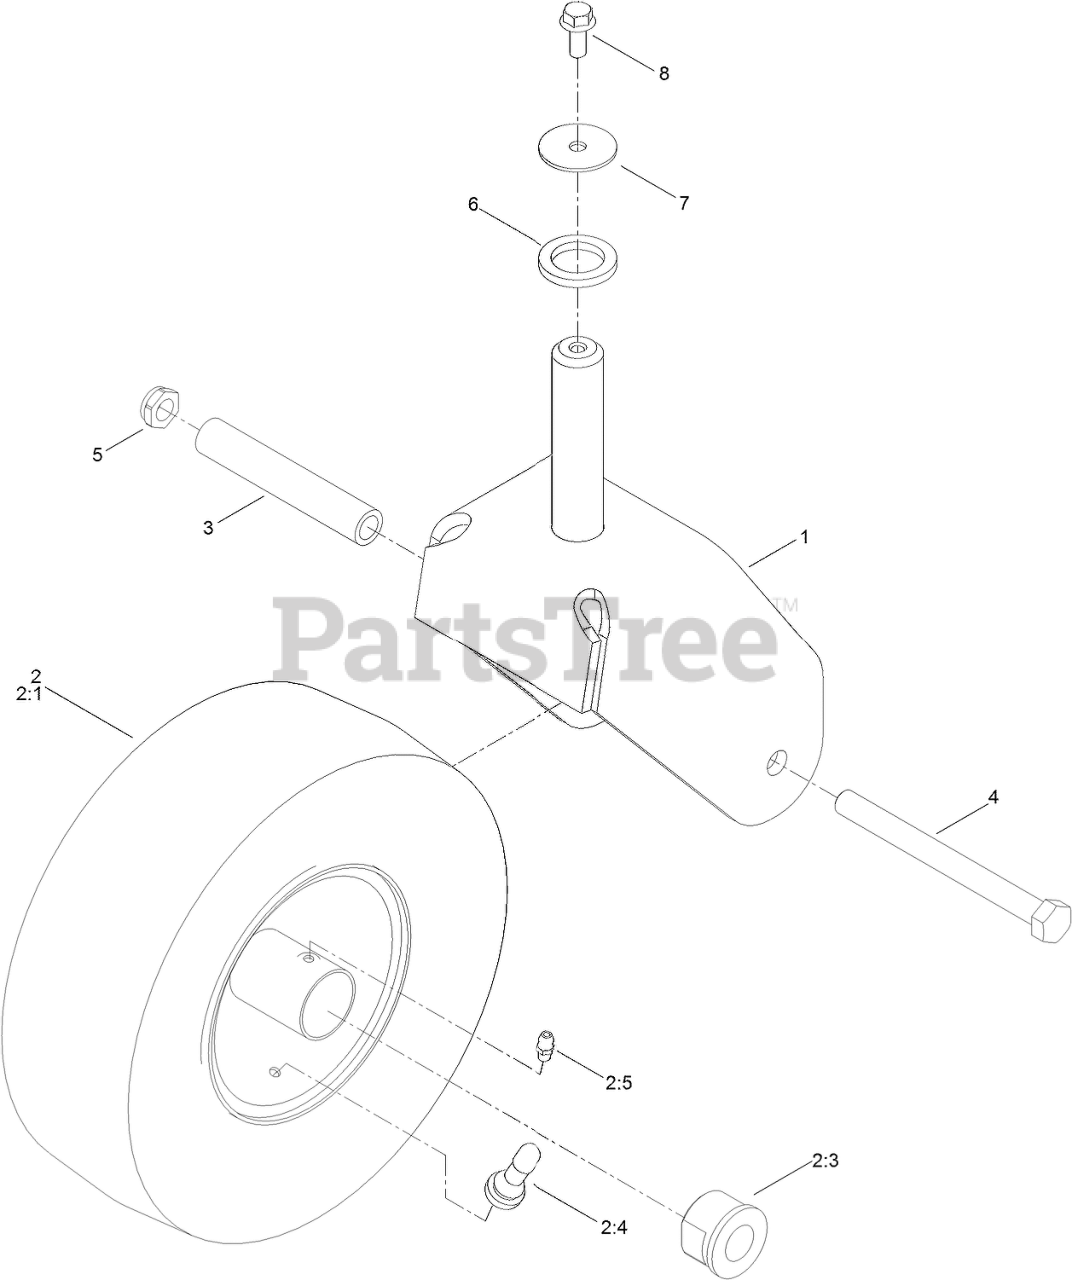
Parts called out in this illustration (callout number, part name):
1	FORK-CASTER
2	CASTER WHEEL ASM
2:3	BUSHING-FLANGE
2:5	FITTING-GREASE
2:6	TUBE-INNER
3	BUSHING-SPANNER
4	SCREW-HH
5	NUT-LOCK, NI
6	WASHER-THRUST
7	WASHER-FLAT
8	SCREW-HHF
